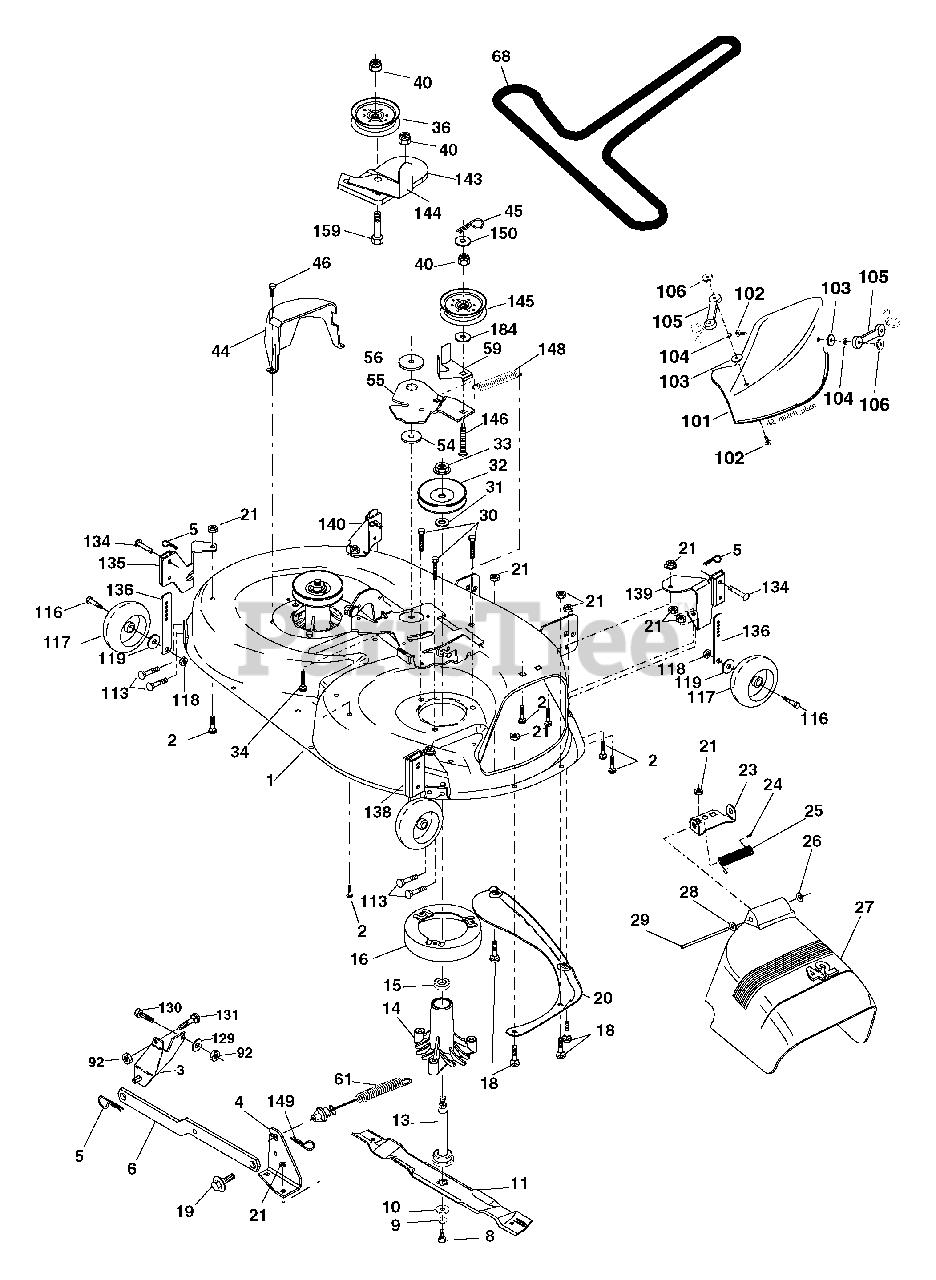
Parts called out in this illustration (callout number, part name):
1	Mower Deck Assembly, 42"
2	Bolt
3	Bracket Asm Fr. Sway Bar 3/42
4	Bracket Asm Deck 42" Sway Bar
5	Retainer Spring
6	Bar Sway Deck
8	Bolt 3/8-24 x 1.25 Gr. 8 patched
9	Washer, Lock
10	Washer, Hardened (The following Blades are available)
11	Blade, Mulching 42" Std
13	Shaft Assembly, Mandrel, Vented
14	Housing, Mandrel, Vented
15	Bearing, Ball, Mandrel
16	Stripper, Mandrel Deck
18	Bolt, Carriage 5/16-18 x 5/8
19	Bolt, Shoulder
20	Baffl e, Vortex
21	Nut
23	Bracket, Defl ector Mower 42"
24	Cap, Sleeve 80 x 112 Blk Mower
25	Spring, Torsion, Defl ector 2 52
26	Nut, Push Phos & Oil
27	Shield, Defl ector 42" Blk
28	Washer 11/32 x 5/8 x 16 Ga.
29	Rod, Hinge 42" 6 75 W/G
30	Screw Thdrol
31	Washer, Spacer Mower Vented
32	Pulley, Mandrel
33	Nut, Toplock
34	Bolt Carr SH 3/8-16 x 1-1/2 Gr.5
36	Pulley, Idler, Flat
40	Nut Lock 3/8-16
44	Guard, Mandrel, LH
45	Retainer
46	Screw, Thdrol 1/4-20 x 5/8 T
54	Washer, Hardened
55	Arm, Idler
56	Spacer, Retainer
59	Guard TUV Idler
61	Spring Ext Elect. Clutch
68	V-Belt, 42" Mower
92	Nut Lock Hex w/Ins. 3/8-16 unc
101	Cover Mulching
102	Screw Pan Hd Phillip
103	Washer #10
104	Washer Lock #10
105	Latch Asm. Mulch/Bagger
106	Nut Weld
113	Bolt 5/16-18 Hex Whs Hd Lckserr
116	Bolt, Shoulder
117	Wheel, Gauge
118	Nut Centerlock 3/8-16
119	Washer 3/8 x 7/8 x 14 Ga.
129	Washer 13/32 x 13/16 x 12 Ga.
130	Bolt Fin HEx 3/8-16 unc x 1 Gr. 5
131	Bolt RDHD SQNK 3/8-16 unc x 1
134	Pin Head Rivet
135	Bracket Asm. Whl Ga. R LH
136	Bar Adjusting Gauge Wheel
138	Bracket Asm Whl Ga. R RH
139	Bracket Asm. Whl Ga. F RH
140	Bracket Asm Whl Ga. F LH
143	Bracket Arm Idler 42"
144	Keeper Belt 42" Clutch Cable
145	Pulley Idler Flat
146	Bolt Carriage Idler
148	Spring Return Idler
149	Retainer Spring Yellow
150	Washer 9/32 x 3/4 x 10 Ga.
159	Bolt Rdhd Sqn 3/8-16 unc x 1-3/4
184	Washer 13/32 x 7/8 x 10 Ga.
